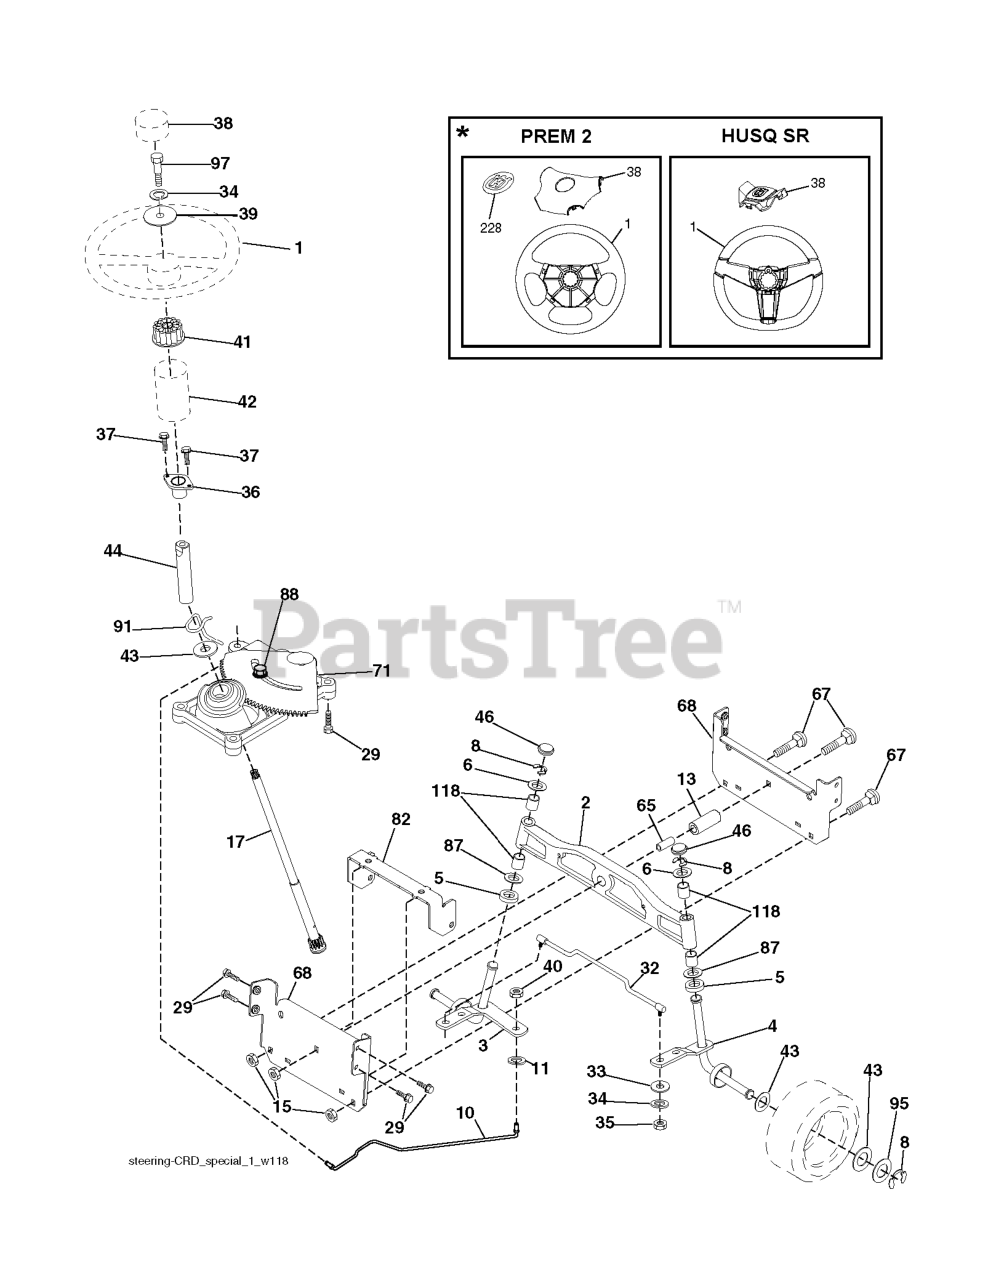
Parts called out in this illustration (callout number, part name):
1	RP WHEEL.STEER.HUSQ.PREM.OVMLD
2	AXLE ASSY FRONT
3	SPINDLE.ASM.LH.15"TIRES
4	SPINDLE.ASM.RH.15"TIRES
5	THRUST WASHER
10	DRAGLINK.15".TIRES.2001
11	WASHER, LOCK 3/8
13	SPACER AXLE
15	NUT
17	SHAFT STEERING SPLINE
29	SCREW, 3/8-16X3/4
33	WASHER M
34	WASHER.LOCK.HVY.HLCL.SPR.5/16
35	NUT, CROWNLOCK
36	BUSHING, STEERING
37	SCREW.TT.#10-32X.5.3/8.FLANGE
38	RP INSERT.CAP.WHL.STRG.HUSQ.
39	WASHER.11/32
40	NUT CROWNLOCK 3/8-24
41	ADAPTER, WHEEL STNG..
42	BOOT, STEERING
44	SHAFT.EXTEN.STRG.SPLINE
46	CAP.SPINDLE.BLACK
65	SPACER BRACE AXLE
67	BOLT CARRIAGE
68	BRACE.AXLE.15"TIRES
71	STEERING ASM
82	BRACKET.SUSP.CHASSIS.FRONT.15
87	WASHER, FLAT .781 X 1 1/2"
88	BOLT, SHOULDER 7/16-20
91	CLIP.STEERING
95	WASHER.HARDENED
118	BUSHING, AXLE CAST
228	DECAL.WHEEL.STRG.LGN.H
